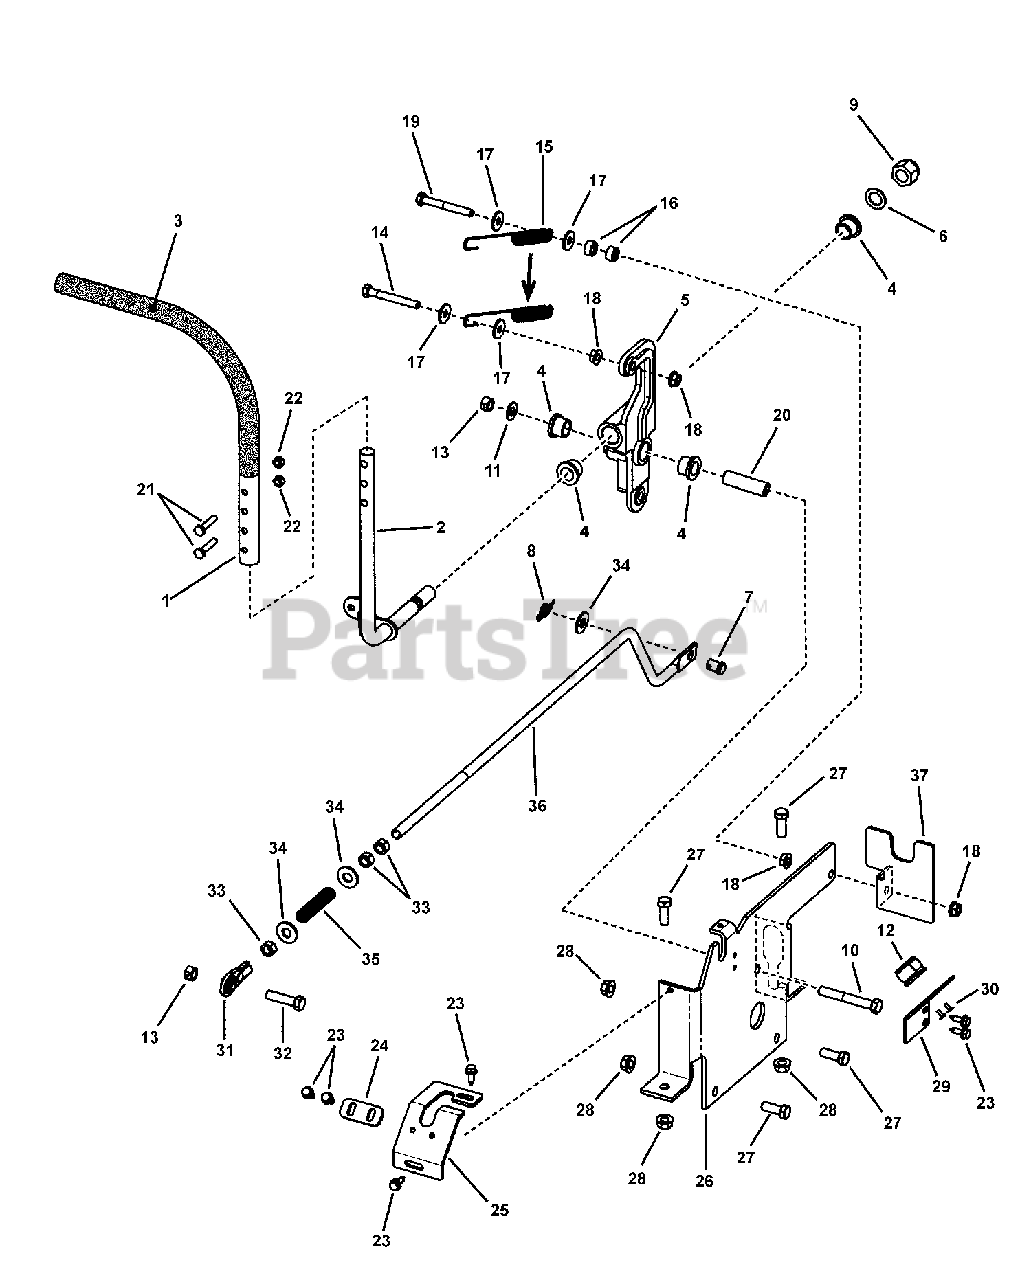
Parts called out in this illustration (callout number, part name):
1	HANDLE
2	WELDMENT, LH Control Arm (5/8" dia. Rod)
3	FOAM GRIP, Handle
4	BUSHING, Bronze, 5/8 x 5/8"
5	CONTROL ARM, LH, Die Cast
6	WASHER, 5/8 ID x 1.00 OD x .065 Nylon
7	CLEVIS PIN, 7/16 x 1"
8	COTTER PIN, 1/2 Self Locking, YZ
9	NUT, 5/8-18 Hex Nyloc
10	SCREW, 3/8-16 x 2-3/4" Hex Head Cap, GR 5
11	WASHER, 3/8" Flat SAE
12	CLIP, Spring
13	NUT, 3/8-16 Hex Center Lock, GR 5 or B, YZ
14	SCREW, 5/16-18 x 2-3/4" Hex Head Cap, GR 5
15	SPRING, Extension, RTN, ERZT
16	SPACER, .34 x .63 x .31
17	WASHER, .33 x .88 x .09 Flat
18	NUT, 5/16-18 Hex Flange Lock, GR 5
19	SCREW, 5/16-18 x 2-1/2" Hex Head Cap, GR 5
20	SPACER, Motor
21	SCREW, 1/4-20 x 1-1/4" Hex Head Cap, GR 5
22	NUT 1/4-20 Hex Center Lock, GR 5 YZ
23	SCREW, 1/4-20 x 3/4" Hex Washer Self-Tap
24	PLATE, Fwd/Rev Adjust
25	TRACK, Control Stick, L.H.
26	CONTROL BRACKET, LH
27	SCREW, 3/8-16 x 1" Hex Head Cap, GR 5, YZ
28	NUT, 3/8-16 Hex Flange Lock
29	BRACKET, Rod Holder, RZT
30	POP RIVET, 1/8 x 3/8"
31	ROD END
32	SCREW, 3/8-16 x 1-1/2" Hex Head Cap, GR 5
33	NUT, 3/8-24 Hex, GR B, YZ
34	WASHER, 7/16" Flat
35	SPRING, Compression (Brake)
36	ROD, Link Fwd./Rev. (3/8-24 thread)
37	BRACKET, LH Fender Support
